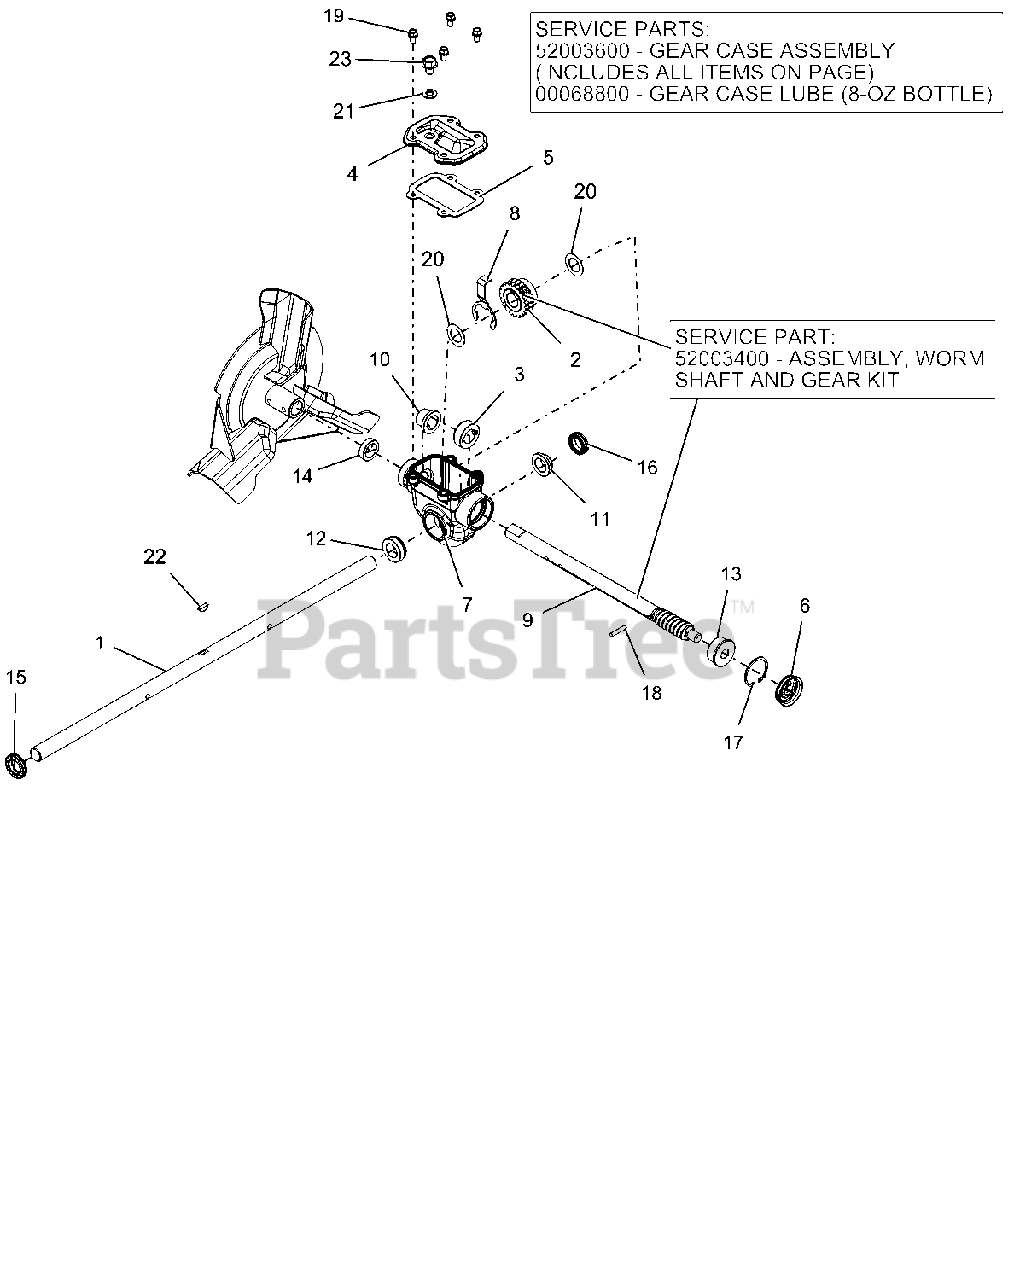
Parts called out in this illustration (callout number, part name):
1	SHAFT, RAKE - 24" (.750 DIA)
2	WORM GEAR
3	THRUST COLLAR, .75" ID SLIPFIT
4	COVER, TOP - COMPACT
5	GASKET, TOP - COMPACT GEARCASE
6	COVER, GEAR CASE 1.50"
7	GEARCASE, COMPACT ALUMINUM
8	BUSHING RETAINER, COMPACT
9	SHAFT, WORM - COMPACT
10	BSHG-FLG .755X.878X.75X1.25
11	BSHG-FLG .755X.878X.424X1.25
12	BSHG-FLG COMPACT, RIGHT
13	BSHG-FLG .503X1.303X.62X1.465
14	SEAL-OIL .748X1.125X.312 TB2-H
15	SEAL-OIL .748X1.300X.250 TBC29
16	SEAL-OIL .748X1.125X.312 TBC29
17	RG-RTNG-INT 1.500X.050
18	PIN-STR .188X1.00 6150
19	BOLT, SEMS .25-20X.50 GR5 YWZC
20	WSHR-FL-STL .760X1.225X.032 YZ
21	WSHR-BND-SEAL .38X.75X.11 GALV
22	KEY-WDRF .19X.63 HRD #61
23	@SCR-ROLOK .38-16X.50 HWH YWZC
24	GEAR CASE, 24" ALUM SM TOP-LD
25	AXLE SHAFT
26	SHAFT AND WORM GEAR ASSEMBLY
